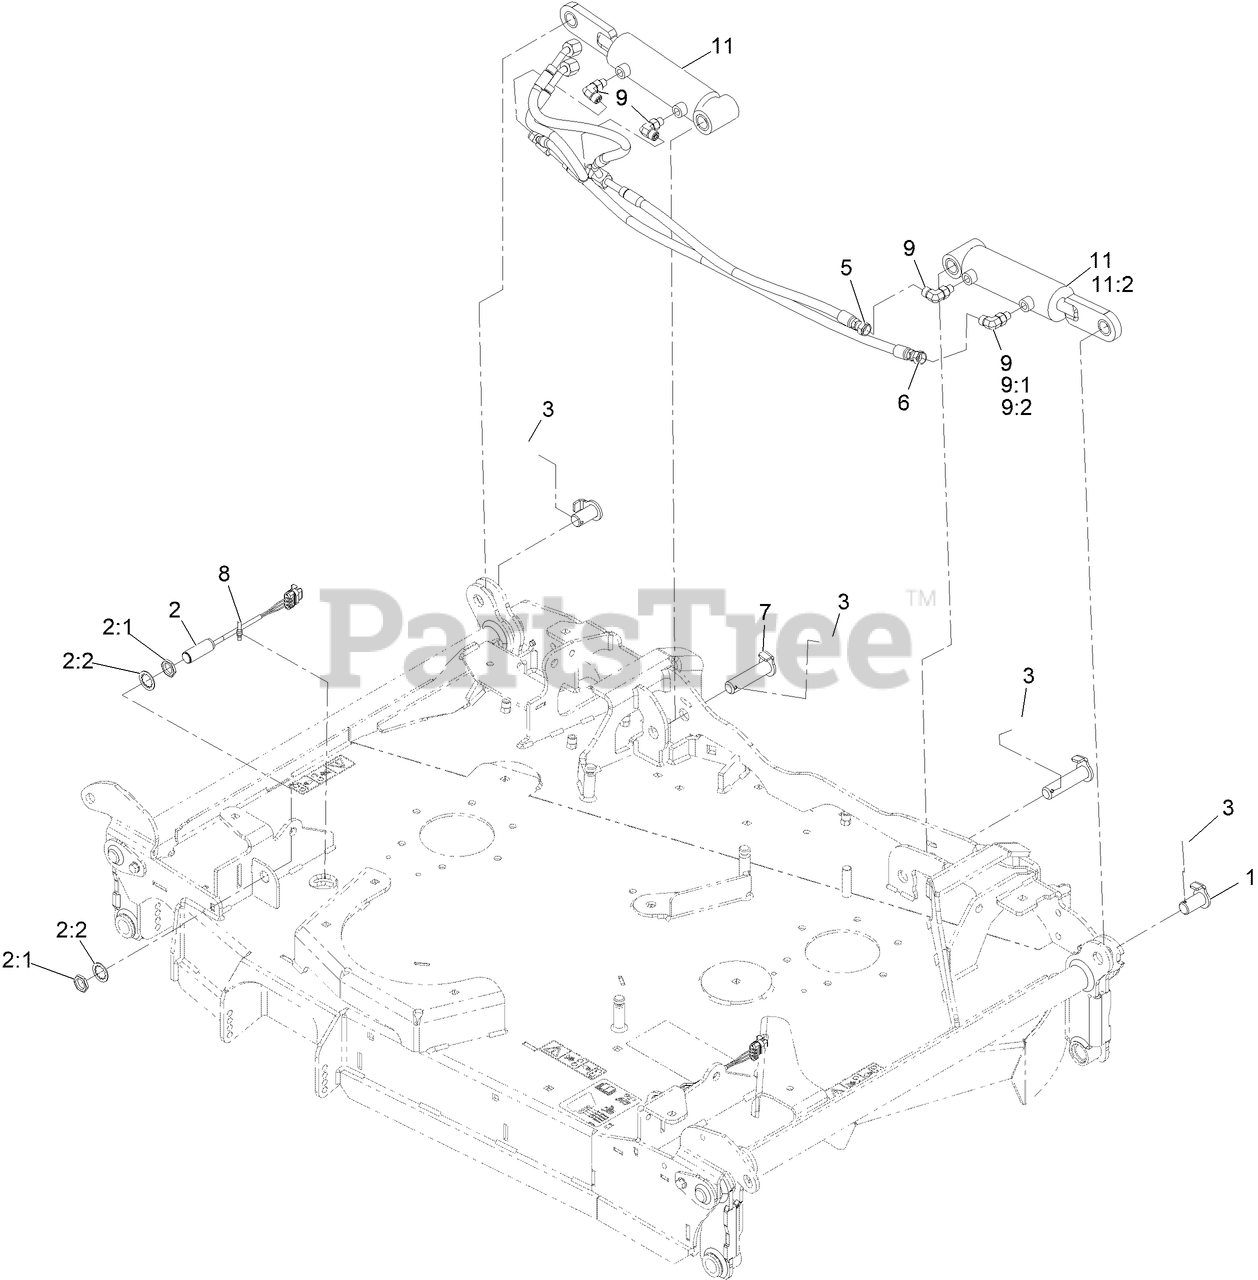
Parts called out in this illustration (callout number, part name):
1	PIN-CYLINDER
2	PROXIMITY SWITCH ASM
2:1	NUT-HEX
2:2	WASHER-LOCK, INTERNAL TOOTH
3	PIN-LOCKING COTTER
5	HOSE ASM
6	HOSE ASM
7	ASM-CYL PIN BASE
8	TIE-CABLE
9	FITTING-ELBOW, 90 DEG
9:1	O-RING
9:2	O-RING
11	CYL-DECK FOLD
11:2	BUSHING-0.75X1.00X0.50 LONG
